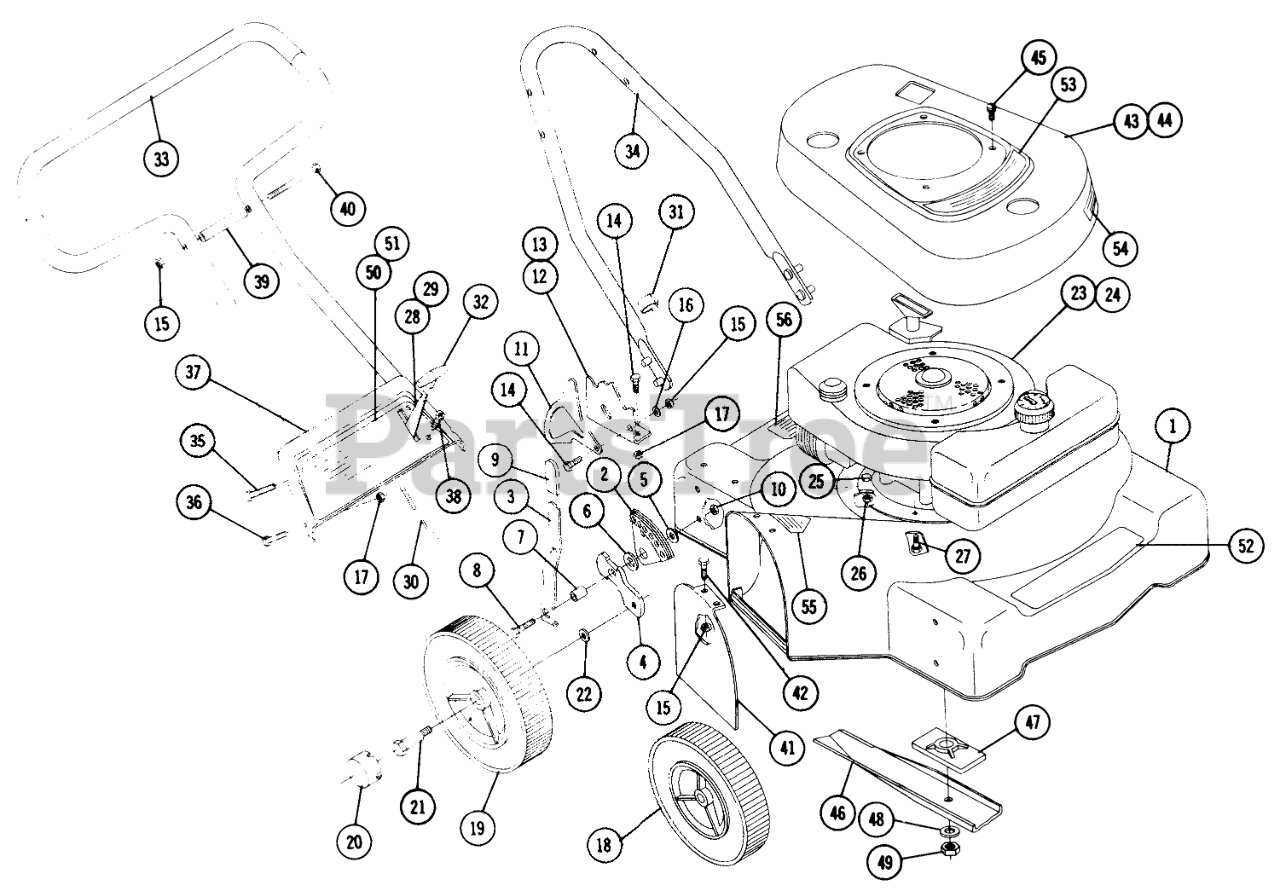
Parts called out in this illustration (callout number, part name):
1	Ass-y. Deck
2	Quadrant-Wheel Bracket
3	Lever-Height Adjustor
4	Arm-Wheel Bracket
5	Washer-Fibre
6	Washer-Fibre
7	Spacer-Bar & Lever Mounting
8	Bolt 3/8-16 x 1
9	Knob-Height Adjustor Lever
10	Nut, Flange 3/8-16
11	Latch-Handle Mounting
12	Bracket Handle R.H.
13	Bracket Handle L.H.
14	Bolt-1/4-20 x 5/8
15	Nut 1/4-20 Nylok
16	Washer
17	Nut Hex 5/4-20 Nylok
18	31000 '60 17 SNWHOU
19	PART CAT OPC
20	Cap-Hub
21	Bolt-Shoulder
22	Washer
23	31000 '60&UP 17 SNO
24	Engine-4 Cycle
25	Bolt
26	Nut-Nylok
27	Screw Hex-Sems 5/16-18 x 3/4
28	Ass-y Throttle Control
29	31100 '60&UP 17 SNW
30	Ass-y. Cable
31	Clip-Control
32	Knob
33	Handle, Upper
34	Ass-y. Handle-Lower
35	Bolt 1/4-20 x 1 1/2
36	Bolt 1/4 20 x 1 1/4
37	Shield-Handle
38	Screw #2 Phillips Sems #8-32 x 1/4
39	20210 '60&UP 21 SP
40	Bolt Hex 1/4-20 x 4 1/2
41	Mulcher-Leaf
42	Bolt, 1/4-x 1/2
43	Shroud-Engine
44	Shroud-Engine
45	Screw Sems 1/4-28 x 3/8
46	Blade 20"
47	Drive Blade
48	Washer, 5/8
49	Nut Hex 5/8-18 Thin
50	Decal-Handle-Challenger II
51	Decal-Handle Challenger IV
52	Decal-Deck
53	Decal
54	Decal-Shroud-Throttle
55	Decal-Caution
56	4XC6485 GIS ROTARY
